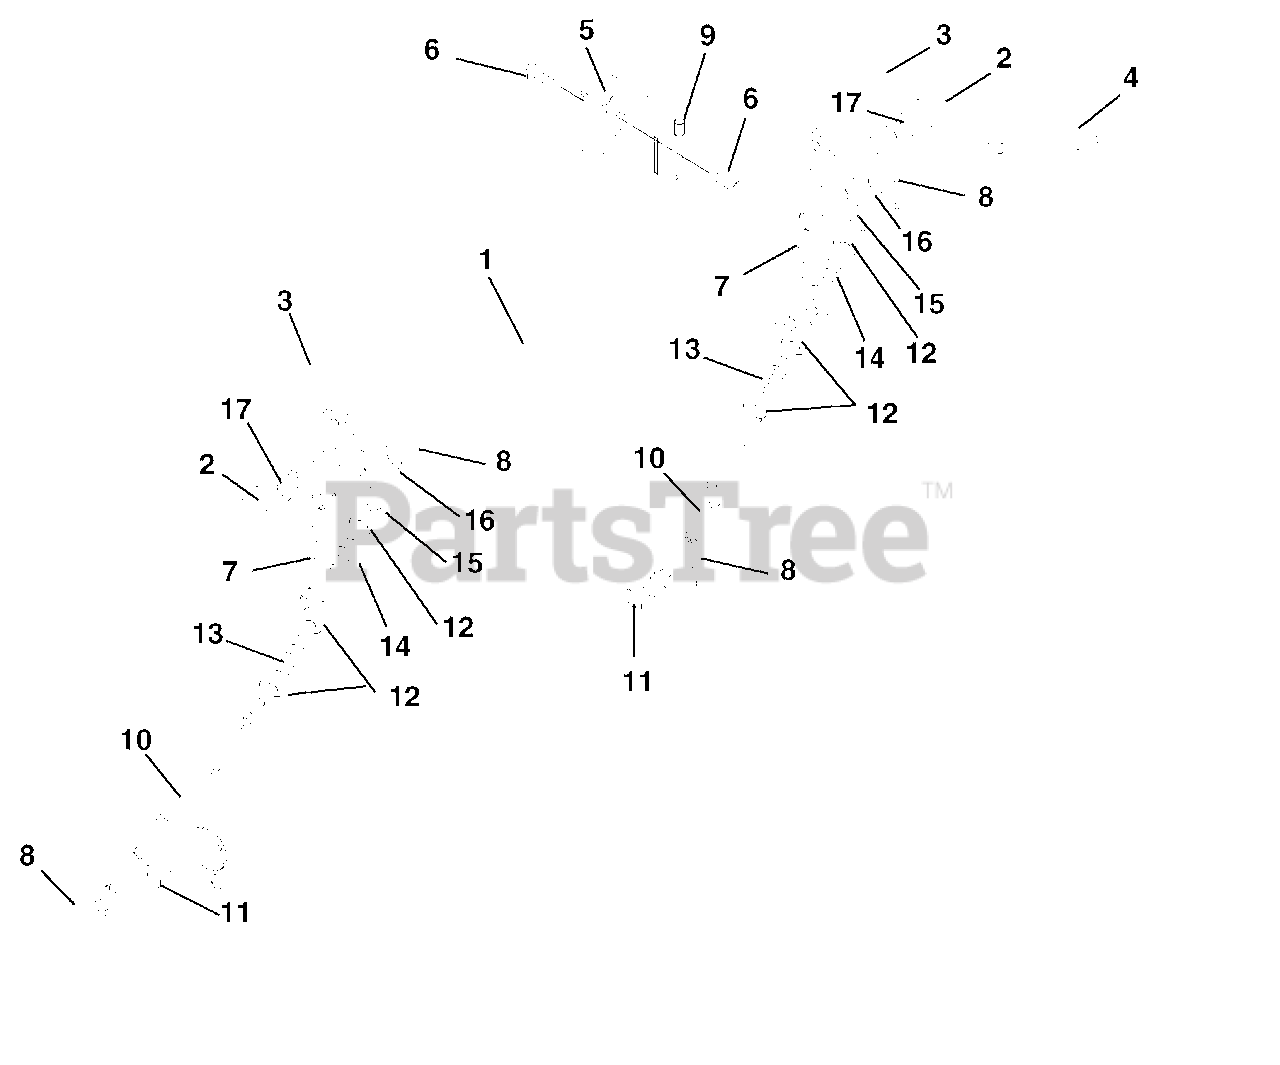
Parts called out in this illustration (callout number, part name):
1	Weldment, Zoom Brake Rod
2	Bushing, Flange .63 x 1.00 x .625 Nylon
3	Pin, Spring Clip
4	Grip, Hand Clutch Lever
5	Bracket, Brake Switch
6	Screw, Tapping 10-24 x .50 Hex Washer Head
7	Rod, Over Center
8	Pin, Hair
9	Switch, Interlock NC
10	Rod, Park Brake
11	Washer, Flat Steel .406 x 1.00 x .188
12	Washer, Flat Steel .344 x .688 x .065
13	Spring, Compression .045 x .50 x 1.187
14	Spring, Compression .063 x .53 x 1.187
15	Nut, Locking Nylon .312-18
16	Washer, Flat Steel .406 x .812 x .065
17	Washer, Flat Steel .627 x .99 x .032
